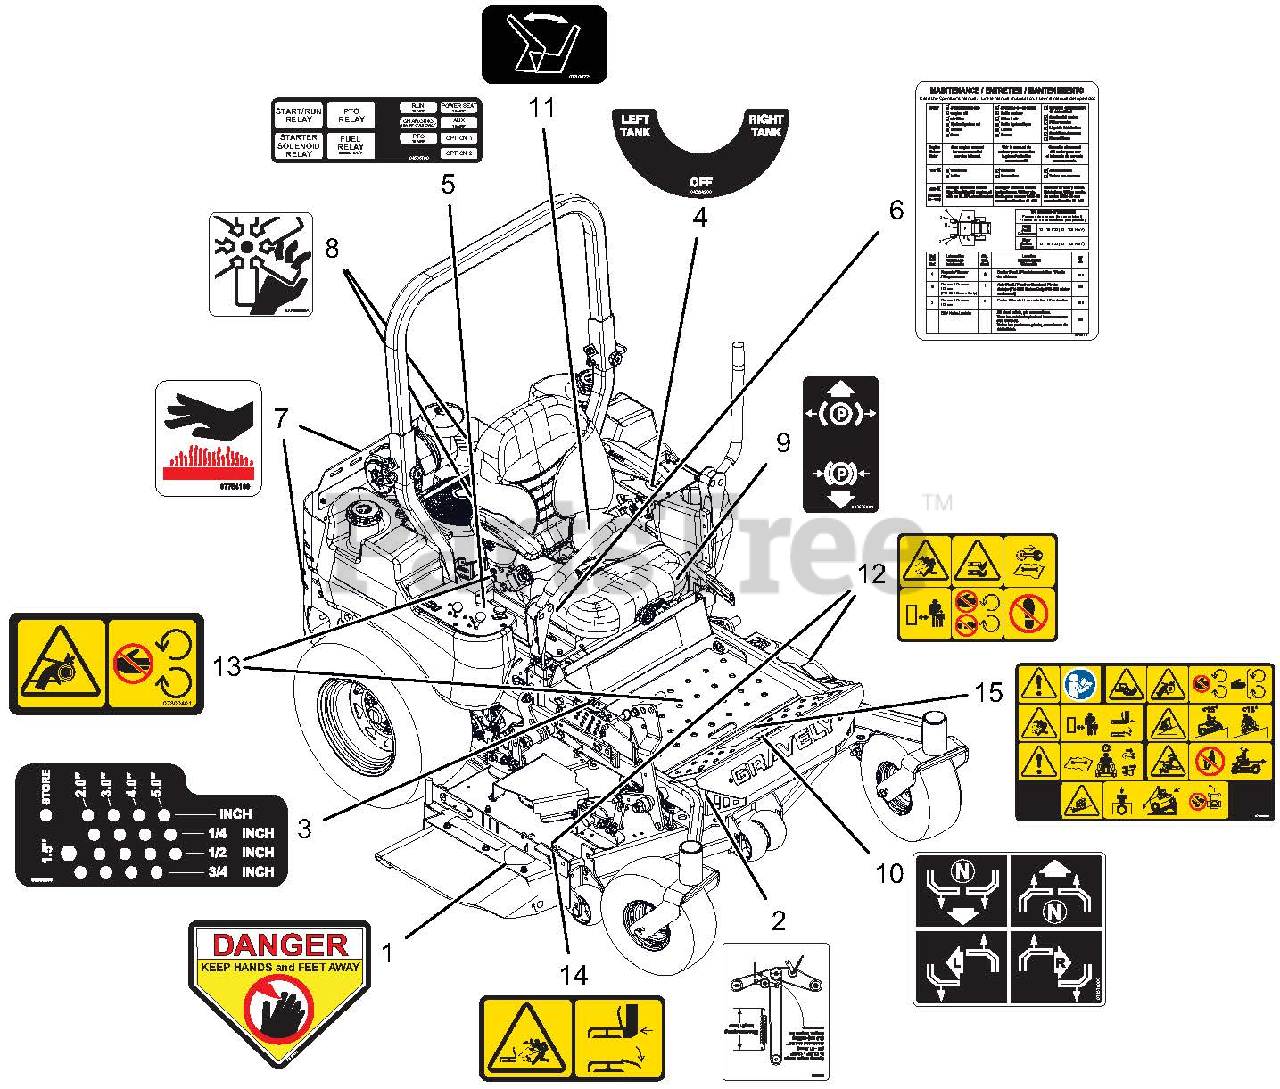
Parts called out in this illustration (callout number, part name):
1	DECAL, DANGER
2	DECAL, BELT ROUTING
3	DECAL, HEIGHT OF CUT
4	DECAL, FUEL VALVE
5	DECAL, FUSE BOX
6	DECAL, MAINTENANCE
7	DECAL HOT SURFACE
8	DECAL, DANGER - FAN
9	DECAL, PARKING BRAKE LEVER
10	DECAL, INSTRUCTIONAL - STEERING
11	DECAL, SEAT RELEASE
12	DECAL, SAFETY - MOWER DECK
13	DECAL, SAFETY - GUARDING
14	DECAL, SAFETY - DECK GUARDING
15	DECAL, MAIN SAFETY, COMMERCIAL
